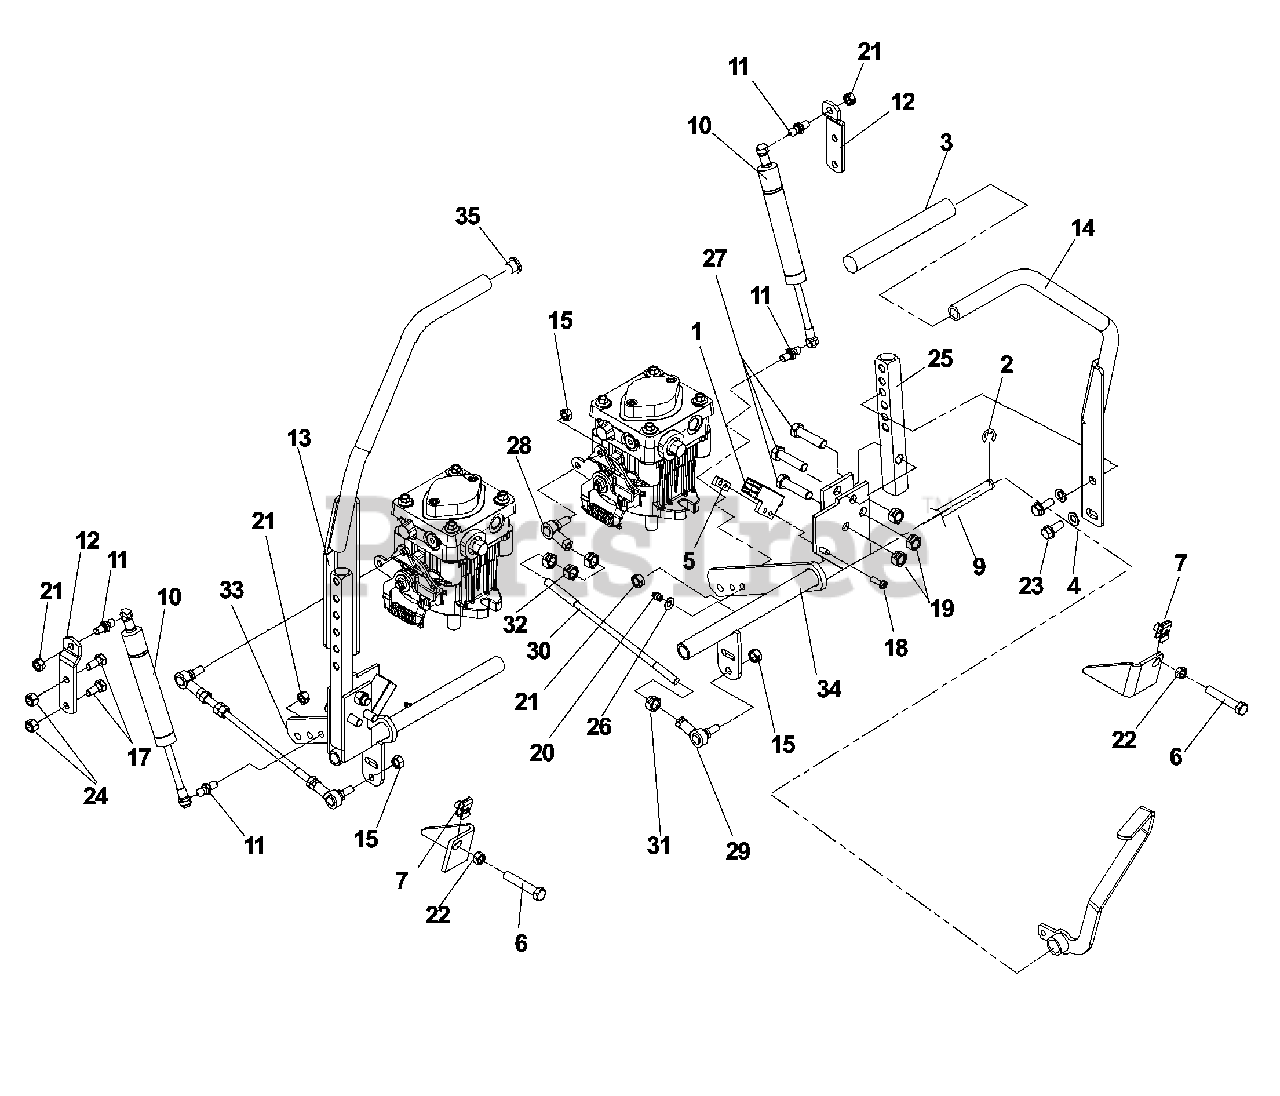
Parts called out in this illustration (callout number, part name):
1	SWITCH, INTERLOCK
2	E-RING 1/2 (2 2)
3	GRIP, FOAM (GROUND) 15
4	WASHER, 3/8 DISC SPRING SPEC
5	TAPPED PLATE
6	HCS 5/16C X 1 1/4
7	U-CLIP 5/16-18 NUT RETAINER
9	CONTROL SHAFT
10	DAMPENER
11	STUD.BALL.10MM
12	DAMPENER ARM
13	LEVER, DRIVE, RT
14	LEVER, DRIVE, LT
15	NUT 5/16F NYLOC
17	HCS 5/16C X 3/4
18	SCREW #10-24 X 5/8
19	NUT 3/8-16 NYLOC
20	ZERK
21	NUT 5/16C CENTERLOCK
22	NUT 5/16C HEX
23	HCS 3/8C X 1
24	NUT 5/16 NYLOC
25	CONTROL ARM
27	HCS 3/8-16 X 1 3/4 GR5
28	SPHERICAL ROD END, RH
29	SPHERICAL ROD END, LH
30	PUMP CONTROL LINK
31	NUT 5/16F LEFTHAND
32	NUT 5/16F
33	DRIVE CONTROL, RT
34	DRIVE CONTROL, LT
35	END PLUG 15/16` (BLACK)
